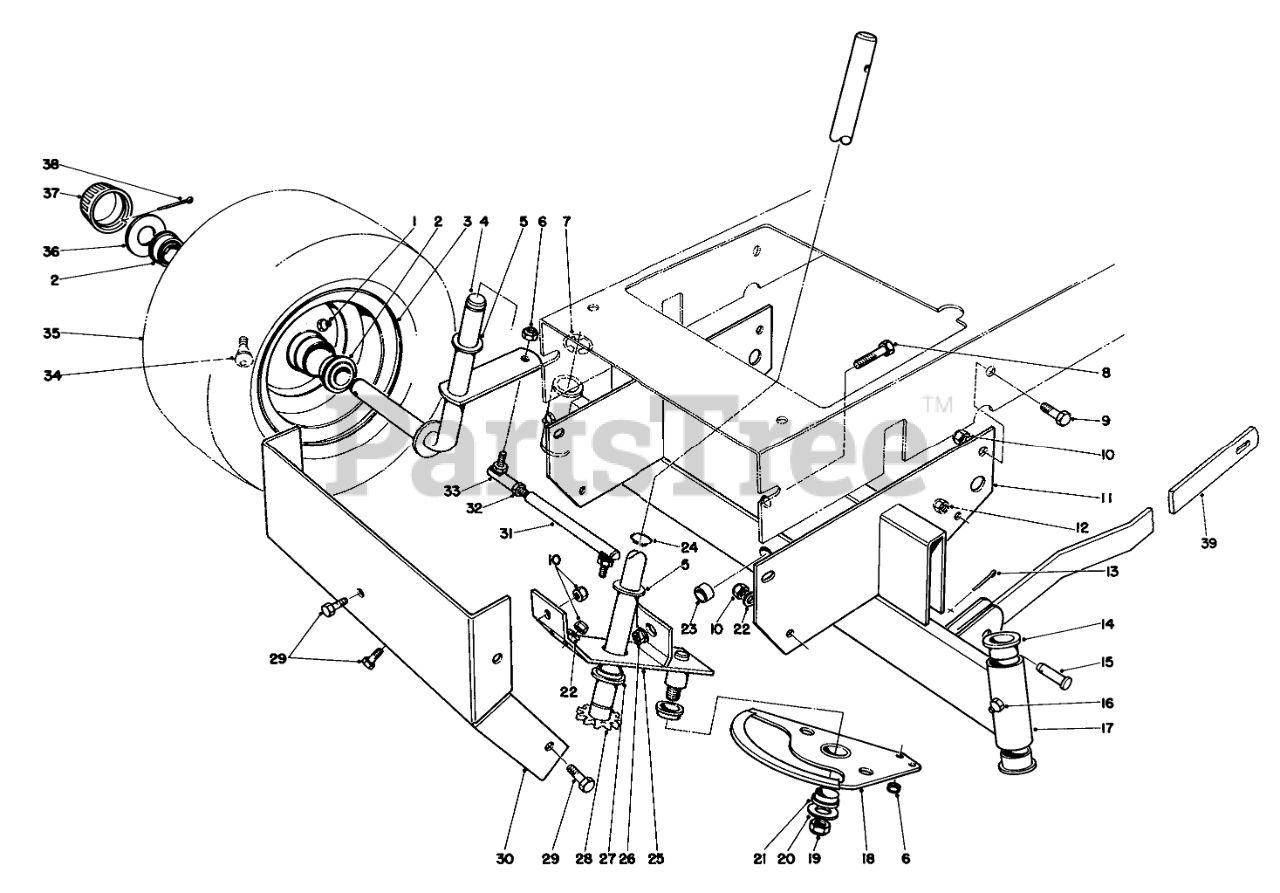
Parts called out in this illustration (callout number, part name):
1	FITTING-GREASE
2	Bearing
4	Spindle RH
5	WASHER-THRUST
6	NUT-LOCK NI
7	E-RING
8	SCREW-HH
9	SCREW-HH
10	NUT-LOCK, CONE
11	Support
12	NUT-LOCK, CONE
13	PIN-COTTER
14	BEARING-FLANGE
15	PIN-CLEVIS
16	GREASE FITTING
17	Axle-Front (Incl. Ref. #14 & 16)
18	Rack-Steering
19	1/2-13 CONELOCK NUT
20	WASHER
21	BEARING-FLANGE
22	WASHER-PLAIN
23	SPACER-AXLE, FRONT
24	RING-RETAINING
25	Rack-Bracket Steering (Incl. Ref. #27)
26	NUT-HF
27	BEARING-FLANGE
28	STEERING SHAFT WA O
29	SCREW-HH
30	Cover-Front
31	Tie Rod-Steering (Incl. Ref. #32 & 33)
32	NUT-JAM
33	JOINT-BALL
34	STEM-VALVE
35	Tire
36	WASHER-PLAIN
37	Cap-Hub
38	PIN-COTTER
39	Arm-Suspension, Front
